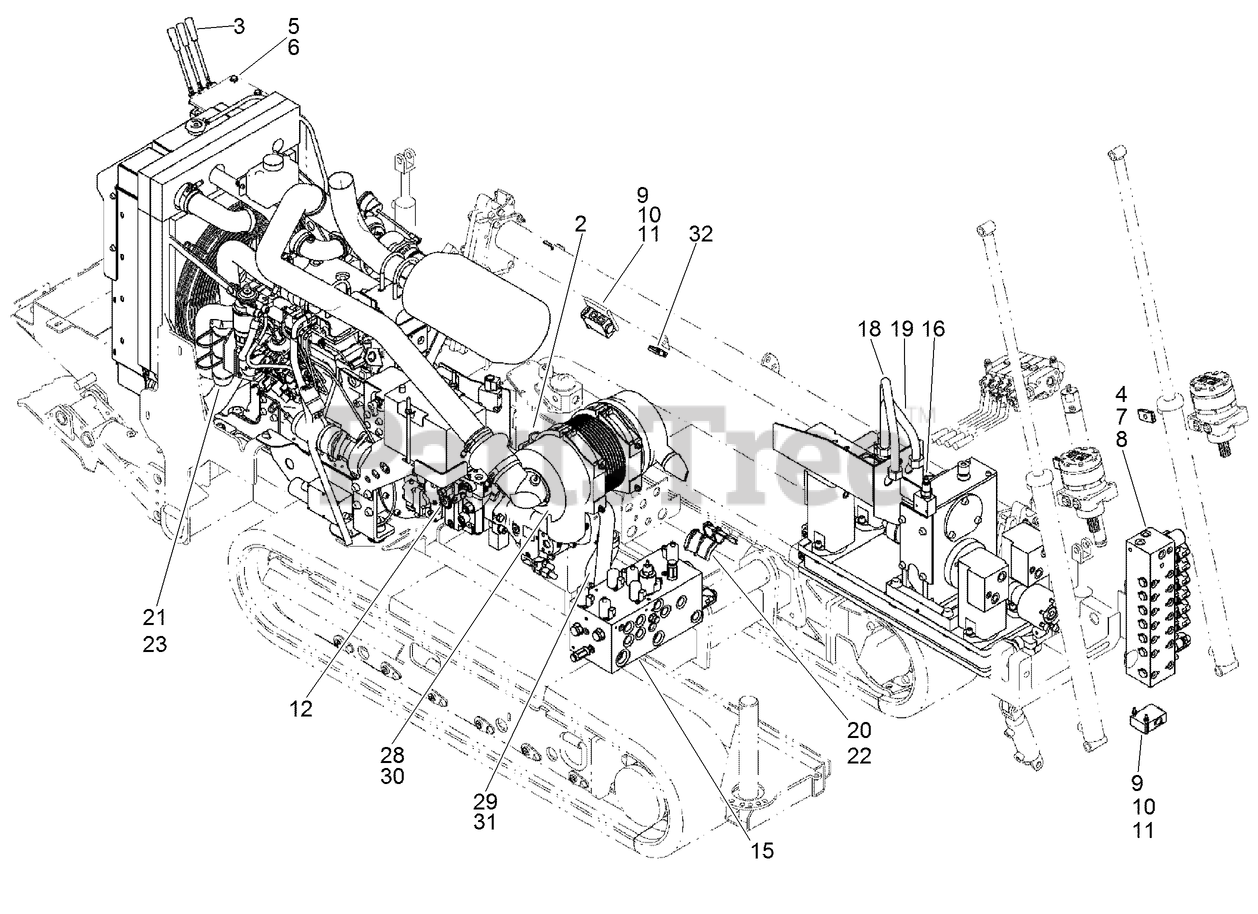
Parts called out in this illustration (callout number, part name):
2	VALVE-THERMOSTAT
3	3 SPOOL HYD VALVE ASM
4	9 SECTION HYD VALVE ASM
5	WASHER-FLAT
6	BOLT
7	WASHER-0.406 x 0.812 x 0.065 in CST ZND
8	SCREW-HH
9	HYD FLOW DIVIDER VALVE ASM
10	SCREW-FLANGE, METRIC
11	NUT, METRIC FLANGE PREVAILING - M6 Zinc
12	VALVE-SHUTTLE, LOAD
15	4 SECTION HYD VALVE ASM
16	PRESSURE RELIEF VALVE ASM
18	TUBE-HYD, HIFLOW (ROTARY B)
19	TUBE-HYD, HIFLOW (ROTARY A)
20	PROTECTOR-HOSE
21	PROTECTOR-HOSE, 8 INCH
22	STRAP-TIE
23	STRAP-TIE
31	CLAMP, T-BOLT
32	CLAMP-HALF (SET OF 2)
